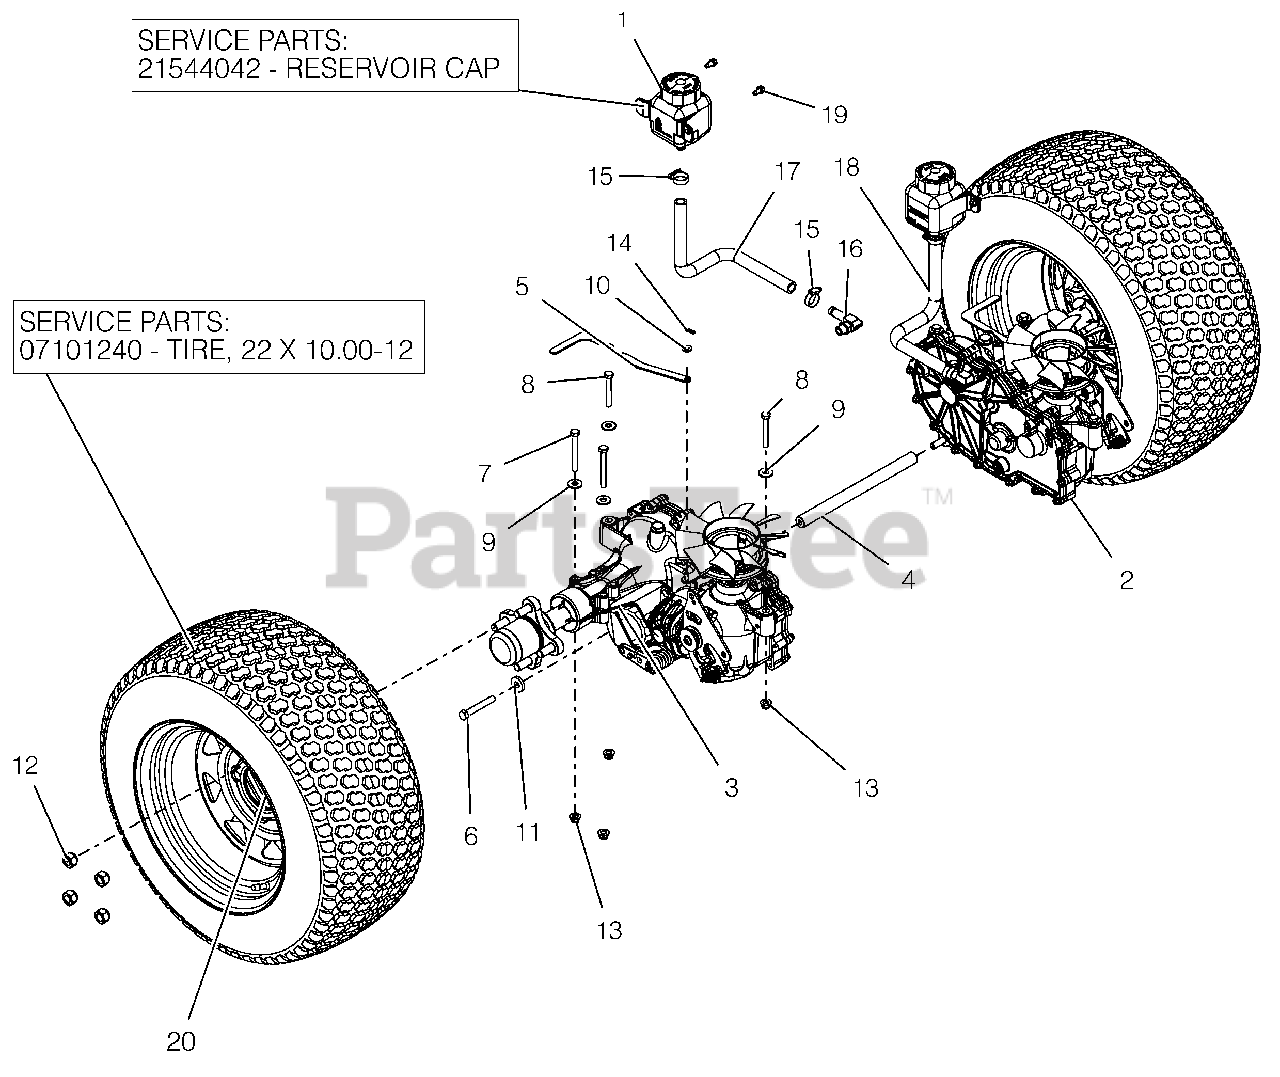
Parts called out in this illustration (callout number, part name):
1	TANK, EXPANSION
1	CAP, HYDRO RESERVOIR REPLAC.
2	TRANSAXLE, ZT3100 LH
3	TRANSAXLE, ZT3100 RH
4	SHAFT, TRANSAXLE SUPPORT
5	BRKT, VALVE DUM
6	@BLT-HEX .38-16X2.50 GR5 YWZC
7	@BLT-HEX .31-18X2.75 GR5 YWZC
8	@BLT-HEX .31-18X2.25 GR5 YWZC
9	@WSHR-FL-STL.38X.875X.083 YWZC
10	@WSHR-FL-STL.281X.62X.065 YWZC
11	WSHR-FL-STL .406X1.00X.188 YWZ
12	WHEEL NUT .500-20 YZ
13	@NUT-LK-NYL-FLG .31-18 YWZC
14	PIN-HAIR, ENDRIES #25 YWZC
15	CLAMP,.88 DIA. HOSE
16	FITTING, HYD (90 DEG)
17	HOSE, FORMED EXPANSION -HD RH
18	HOSE, FORMED EXPANSION -HD LH
19	SCR-TAP .25-20X.50 HWH TR YWZ
20	ASM, WHL/TIRE 22X10.00-12 K500
20	TIRE, 22X10.00-12
